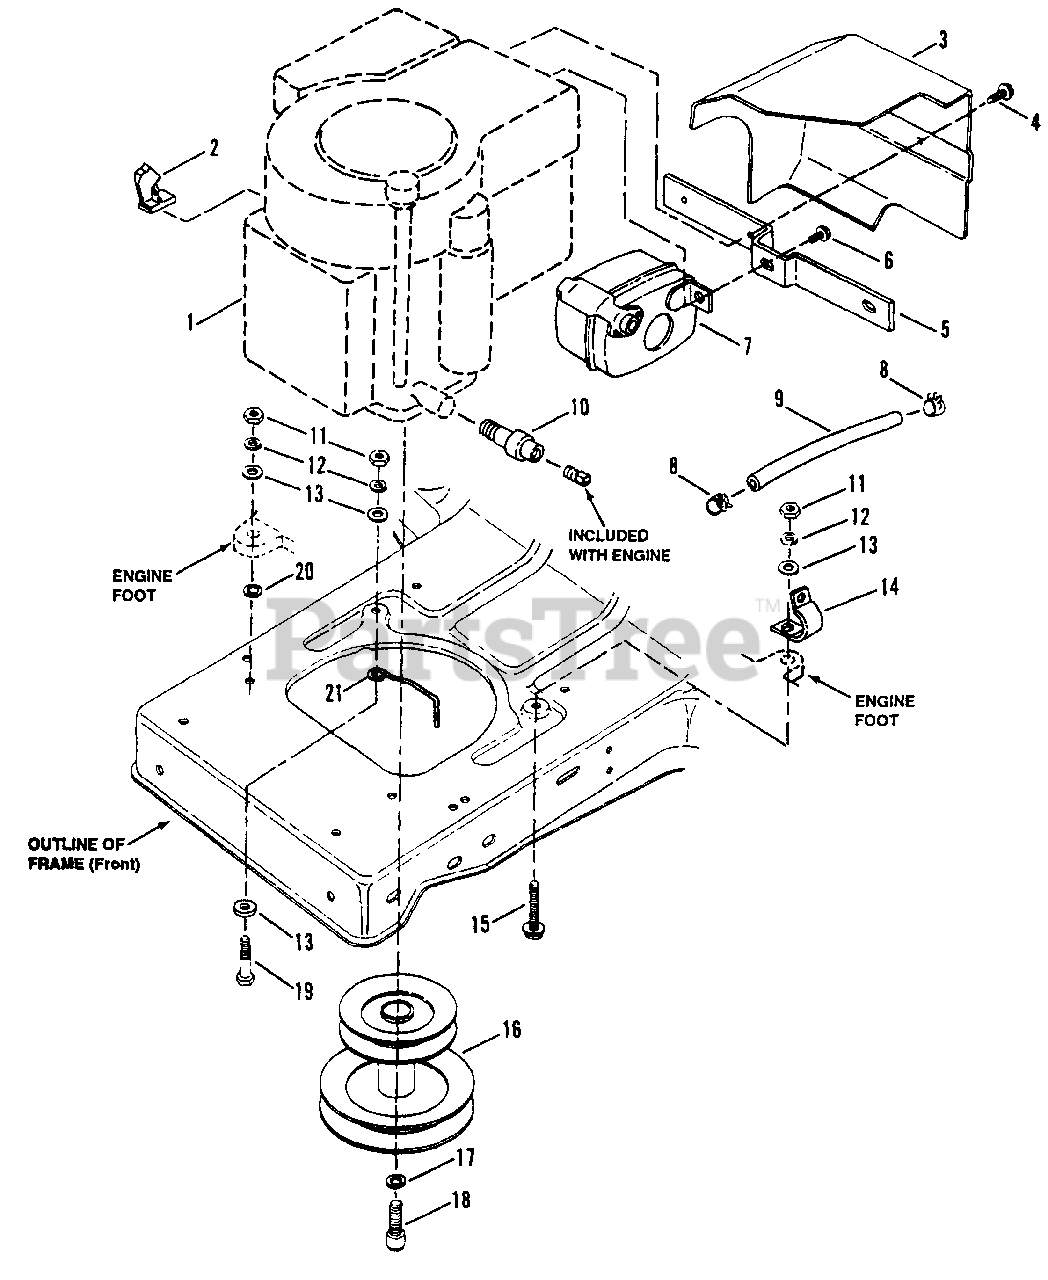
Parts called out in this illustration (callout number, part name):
2	CLIP, Speed
3	HEAT SHIELD
4	SCREW, #10-24 x 1/2" H.W.H.S.T.
5	BRACKET, Heat Shield
6	BOLT, 1/4-20 x 1/2" Hex Flange Lock
7	MUFFLER, Exhaust
8	CLAMP, Fuel Line
9	LINE, Fuel, 7" Long
10	EXTENSION, Oil Drain (Short)
11	NUT, 5/16-18 Hex
12	WASHER, 5/16 Split Lock
13	WASHER, 5/16 Flat
14	CLIP, Harness
15	SCREW, 5/16-18 x 1 1/2" H.H.C.
16	PULLEY ASSEMBLY
17	WASHER, 7/16 Split Lock
18	SCREW, 7/16-20 x 1" H. C., Sk. Hd.
19	SCREW, 5/16-18 x 1 3/4" H.H. Cap
20	WASHER, 5/16 Internal Tooth Lock
21	GUIDE, Belt
